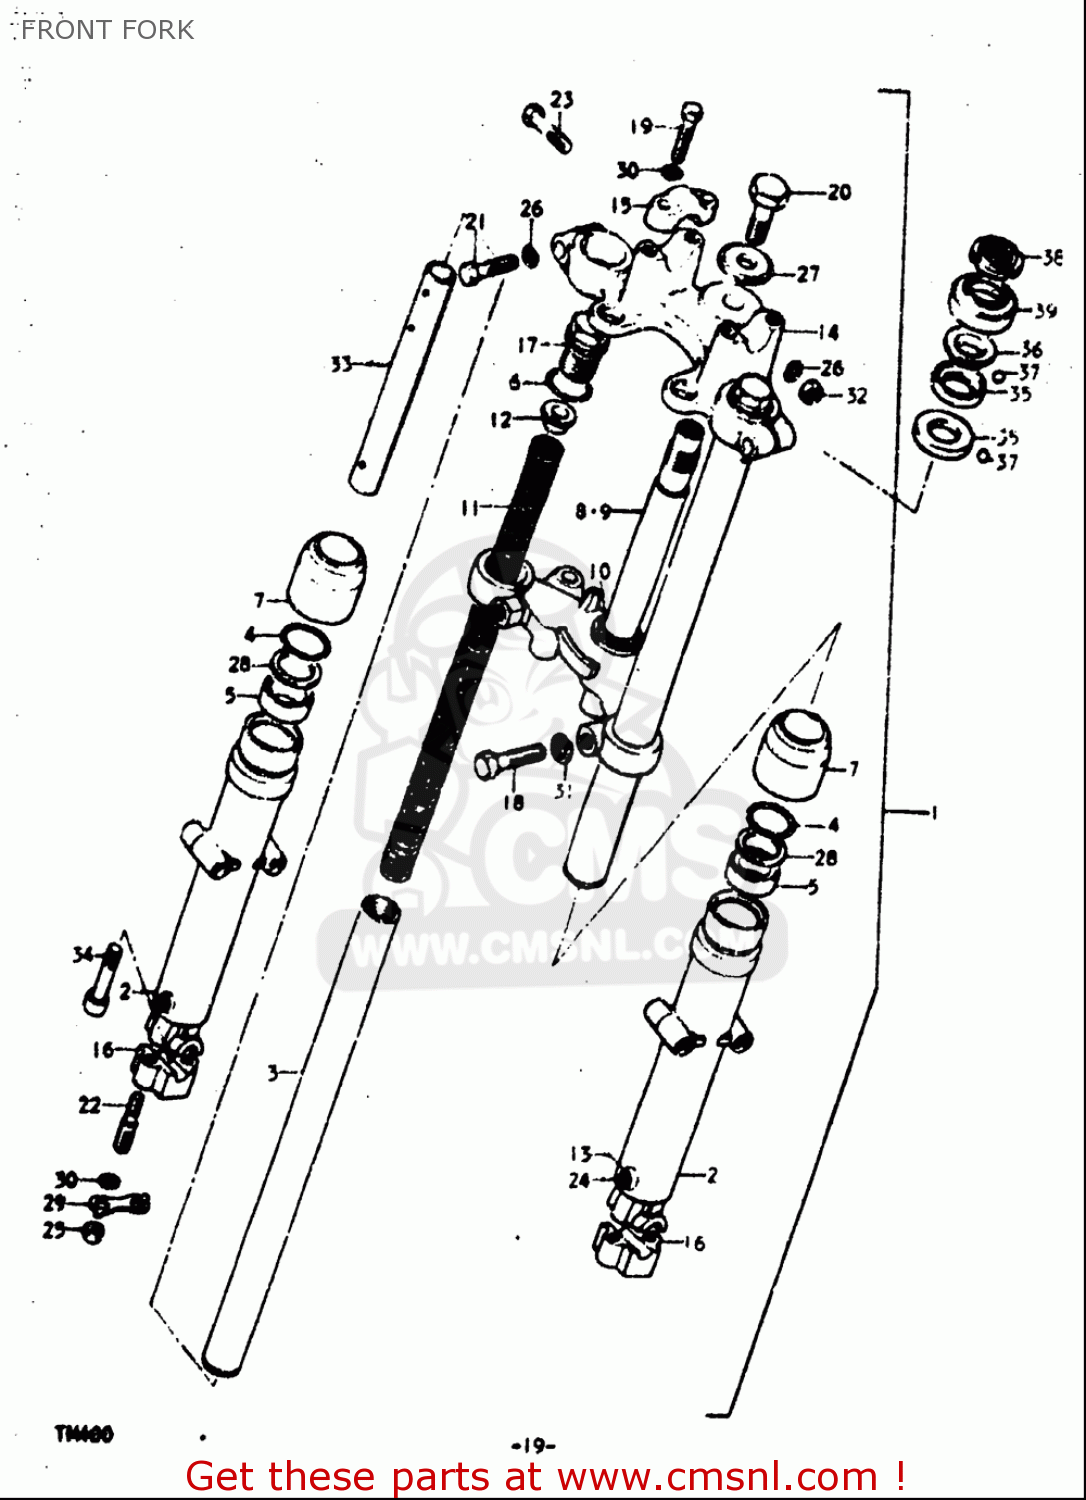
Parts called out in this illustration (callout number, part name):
5	SEAL,OIL
6	O RING
10	RACE,STEERING OUTER LWR
13	GASKET,DRAIN,PLUG (NAS)
15	HOLDER,HANDLEBAR
19	BOLT
20	BOLT,FR FORK(10X33)
21	BOLT
22	BOLT,STUD
23	BOLT
24	SCREW
25	NUT
26	WASHER,LOCK
27	WASHER
28	WASHER, OIL SEAL
30	WASHER,LOCK
31	WASHER,LOCK
32	NUT
34	BOLT,FORK CYLINDER(10X25)
35	LACE,STEERING INNER LWR
36	LACE,STEERING OUTER UPR
37	BALL
38	NUT,STEERING STEM(25X44X10)
39	DUST SEAL,STEERING UPR
